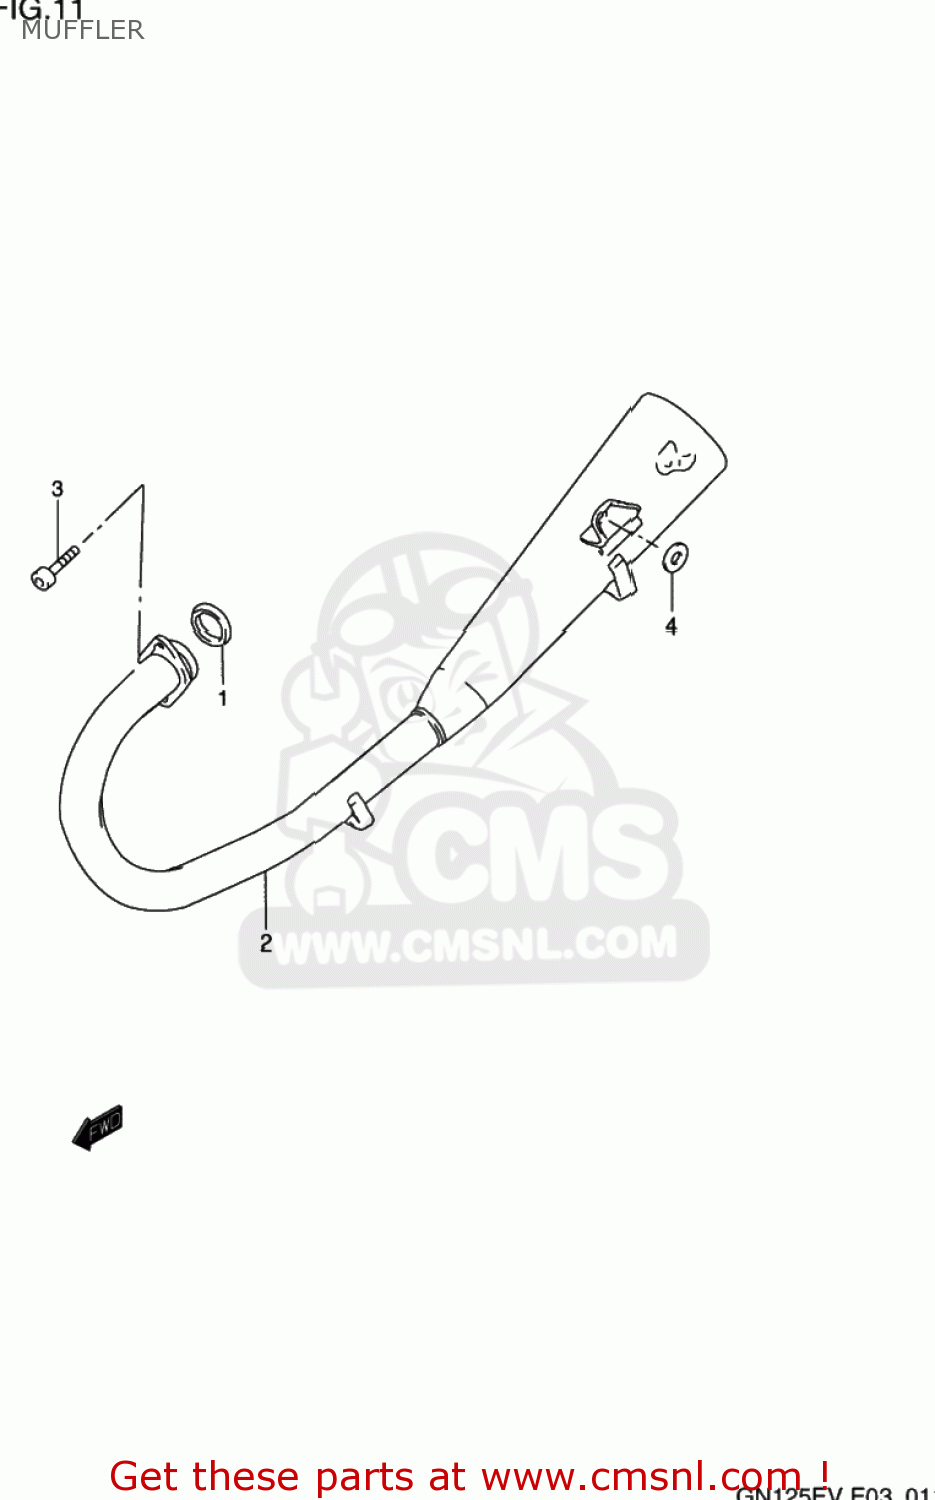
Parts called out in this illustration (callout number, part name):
1	GASKET,EXHAUST (NAS)
2	MUFFLER ASSEMBLY
3	BOLT
4	WASHER
